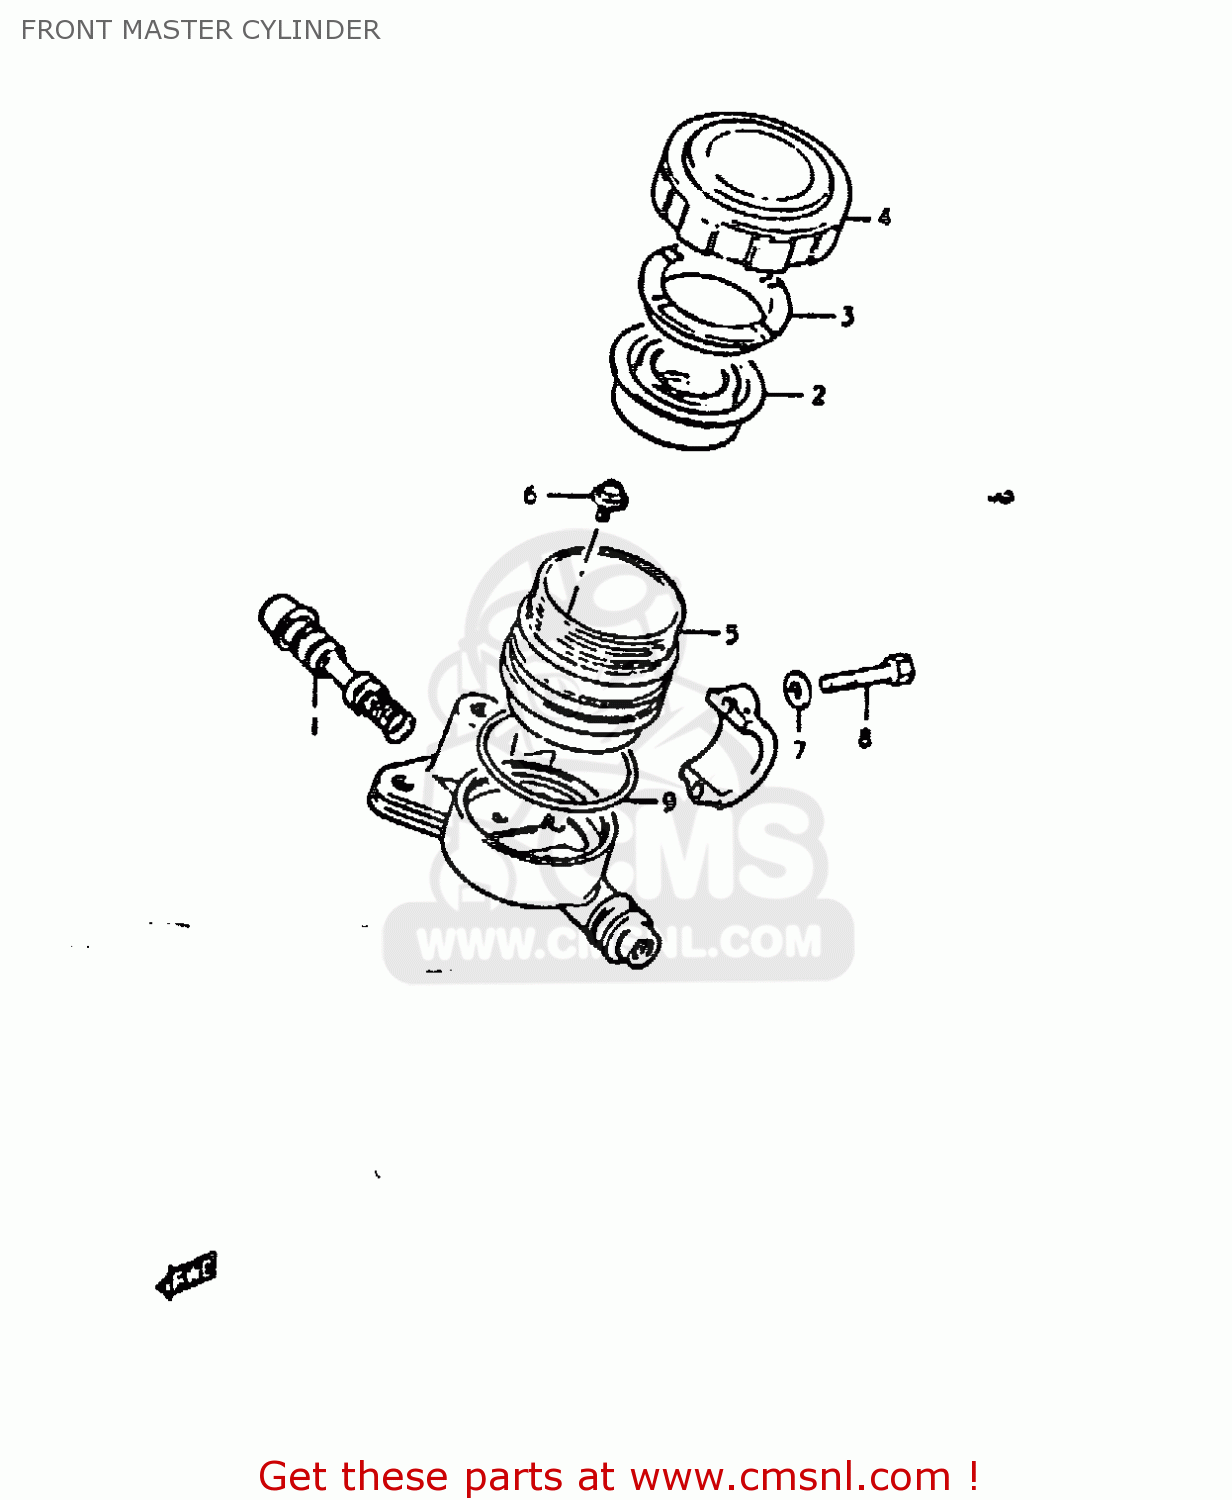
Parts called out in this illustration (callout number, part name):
1	PISTON & CUP SET
2	DIAPHRAGM
3	PLATE
4	CAP
5	RESERVOIR
6	SCREW,MASTER CYLINDER
7	WASHER
8	BOLT
9	O RING
